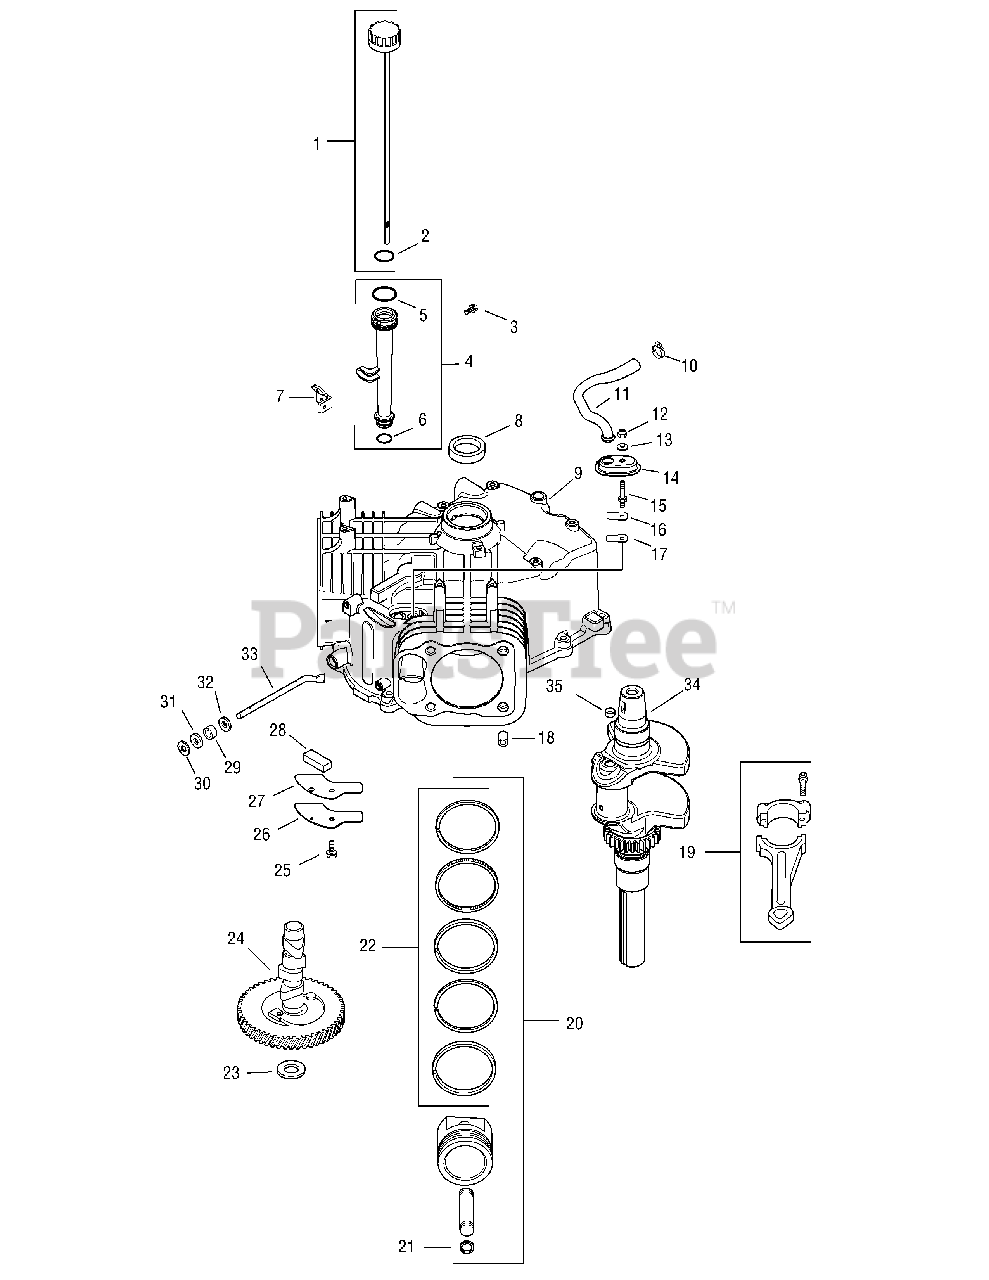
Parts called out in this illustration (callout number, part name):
1	Kit, dipstick (Includes 2)
2	O-Ring
3	Screw, hex. flange thread forming
4	Tube, oil fill (Includes 5,6)
5	O-Ring, upper oil fill tube
6	O-Ring, lower oil fill tube
7	Bracket, oil fill tube
8	Seal, oil
9	Crankcase
10	Clamp, hose
11	Hose, breather
12	Nut, hex. lock M5x0.8
13	Washer, sealing
14	Housing, breather
15	Stud, breather cover
16	Retainer, breather reed
17	Reed, breather
18	Pin, locating
19	Connecting Rod (Std.)
20	Piston w/Ring Set (Std.) (Includes 20,21)
20	Piston w/Ring Set (.25) (TBD)
21	Retainer, piston pin
22	Ring Set (Std.)
22	Ring Set (.25)
23	Shim, camshaft (yellow)
23	Shim, camshaft (red)
23	Shim, camshaft (black)
23	Shim, camshaft (white)
23	Shim, camshaft (blue)
23	Shim, camshaft (green)
23	Shim, camshaft (gray)
24	Kit, camshaft
25	Screw, hex. flange thread forming
26	Cover, breather
27	Gasket, breather cover
28	Filter, breather
29	Seal, governor cross shaft
30	Ring, retainer
31	Washer, plain 8 mm
32	Washer, flat 1/4"
33	Shaft, governor cross
34	Crankshaft (Includes 2)
35	Plug, cup
